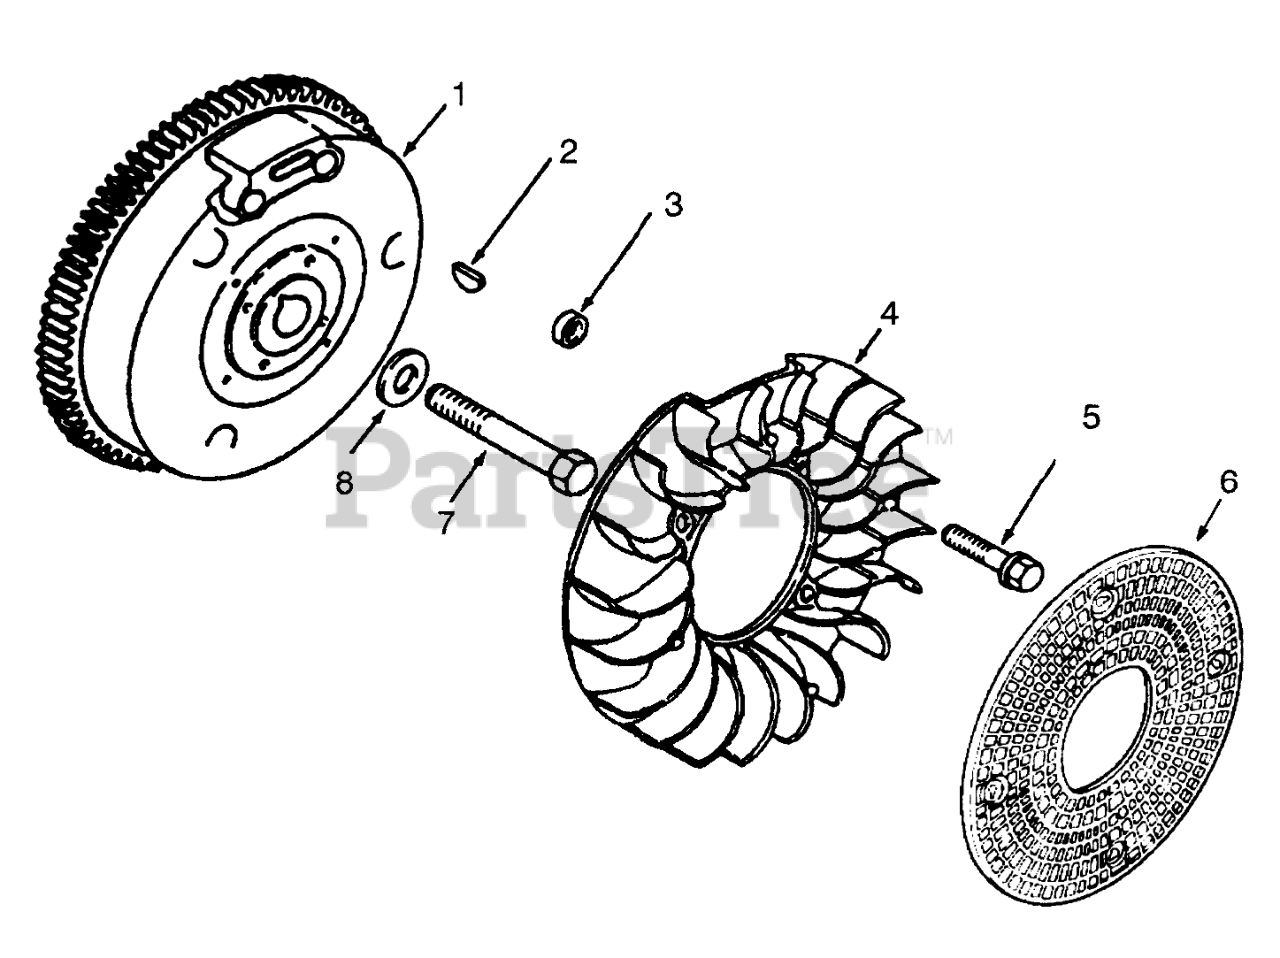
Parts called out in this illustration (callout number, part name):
1	Flywheel
2	Key-Woodruff
3	Spacer
5	Screw-Hex. Hd.
6	Screen
7	Screw
8	Washer
